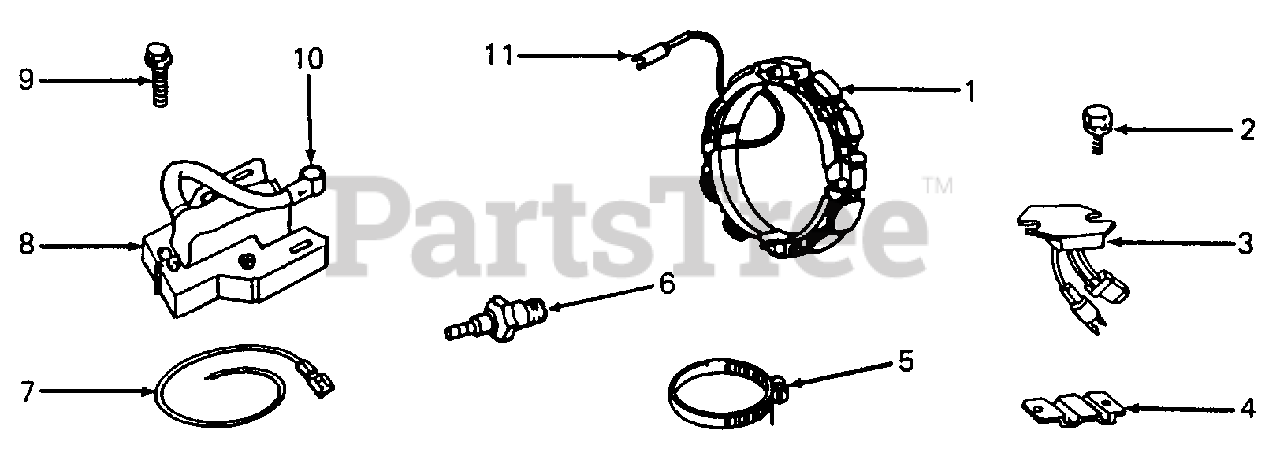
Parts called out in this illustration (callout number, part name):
1	Stator, Alternator
2	Screw, Regulator Mounting
3	Regulator, Alternator
4	Bracket, Regulator
5	Clamp, Regulator
6	Spark Plug
7	Wire, Ground
8	Armature Assy, Magneto
9	Screw, Armature Mounting Sem
10	Terminal, Ignition Cable
11	Connector Assy
